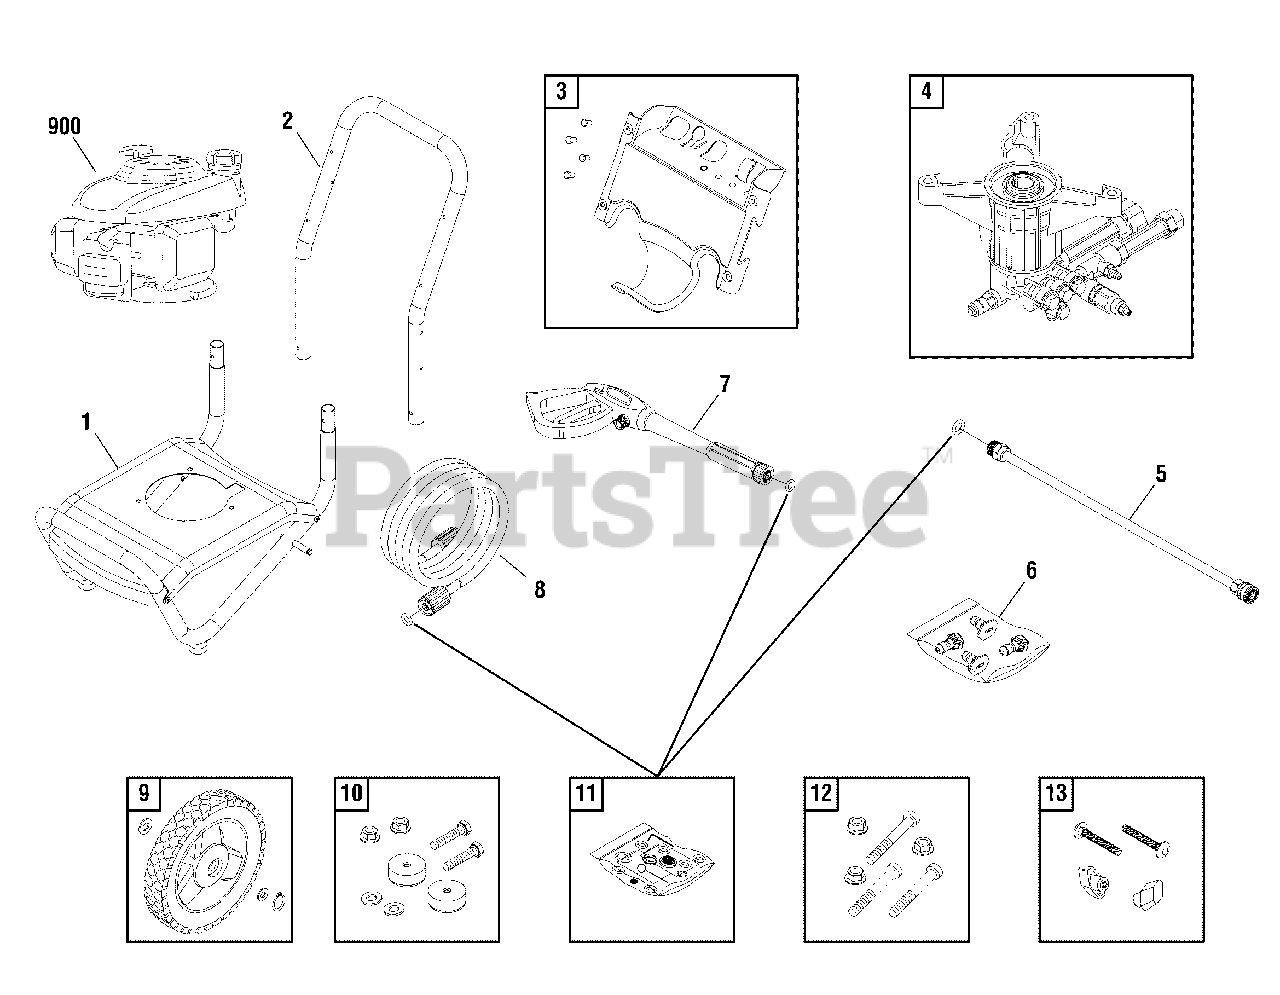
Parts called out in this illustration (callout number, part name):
7	GUN
8	HOSE
10	MOUNT-VIBRATION
12	KIT-HARDWARE PUMP MOUNTING
13	KIT-HARDWARE HANDLE
900	* ENGINE
